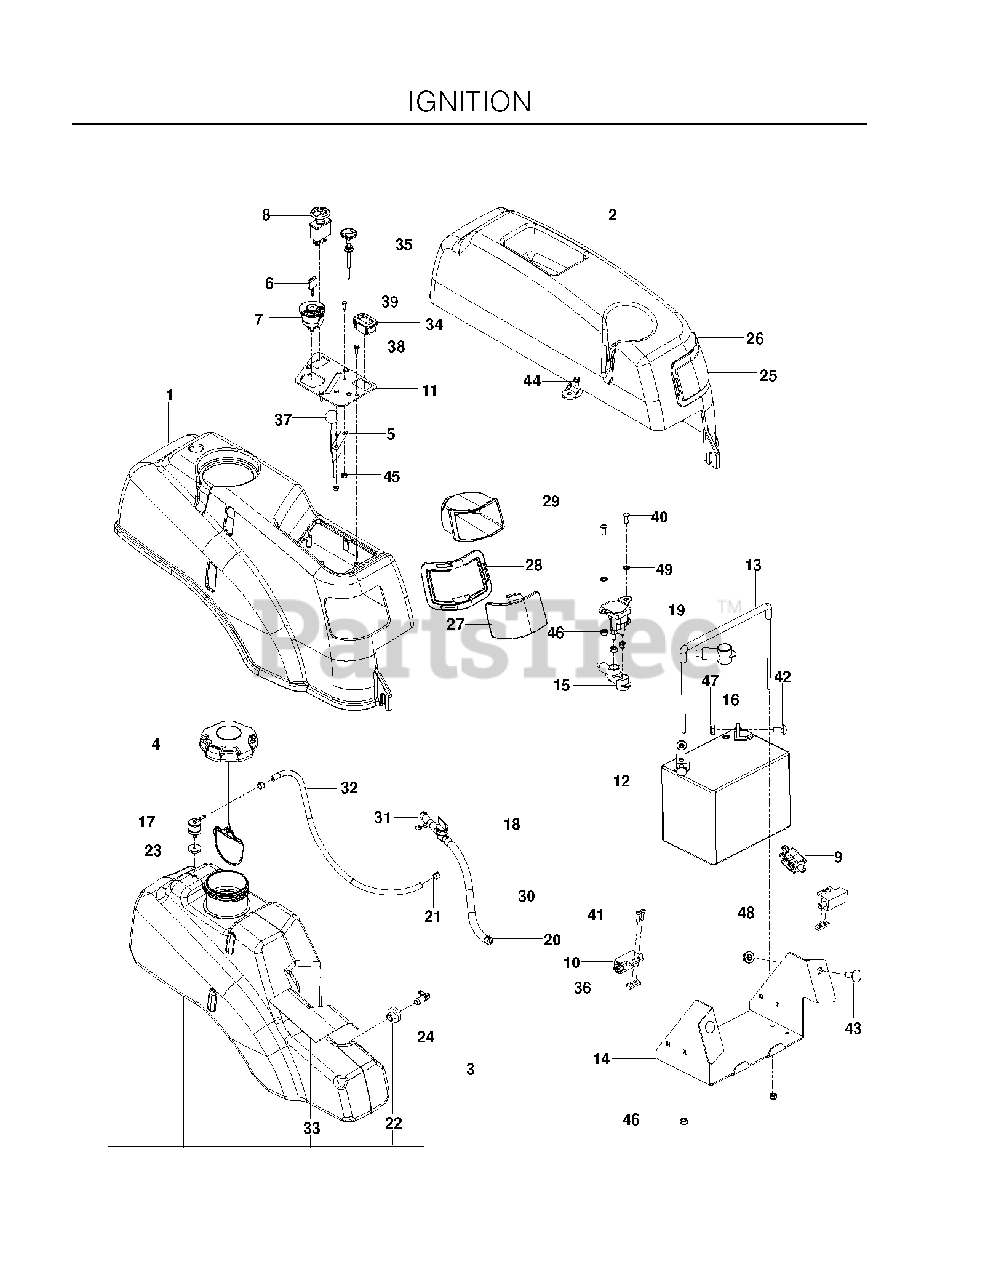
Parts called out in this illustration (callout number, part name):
2	FENDER, LT, BLK
4	CAP, FUEL
5	THROTTLE CONTROL W/BALL KNOB
7	IGNITION SWITCH
9	SWITCH, BRAKE 3P
12	BATTERY, 12 V 330 AMP
13	BATTERY TIE DOWN ASSEMBLY
14	BOX, BATTERY, BLACK
15	TERMINAL COVER-SM
16	INSULATOR
17	VALVE, FUEL CHECK
18	FUEL VALVE
19	SOLENOID
20	HOSE CLAMP
21	CLAMP, HOSE
22	RUBBER GROMMET
23	GROMMET, CHECK VALVE
25	LEFT HEADLIGHT LENS
26	RING, LT BLK
27	RT HEADLIGHT LENS
28	RING, TRIM, RT-BLK
30	GAS LINE 10"
31	FUEL LINE - 2.5"
32	HOSE, VAPOR 3/16 X 15"
34	HOUR METER
36	TAPPED PLATE
37	KNOB ROUND BALL
38	SCR #10-12X3/4 HEX WAS HD ZD
39	HCS #10-24 X 1/2
40	SCR 1/4-20 X 5/8 BTN SKT HD ZD
41	SCR #10-24 X .75 SKT HD BLK
42	BOLT 5/16C X 3/4" CARRIAGE
43	RHSNB 3/8C X 1
44	BOLT 1/4-20 X 1/2 HWST
45	NUT 10-24 NYLOC
46	NUT 1/4-20 NYLOC
47	5/16-18 NYLOC FLANGE NUT
48	NUT 3/8-16 HEX FLG NYLOC ZD
49	WASHER 1/4 INT TOOTH
